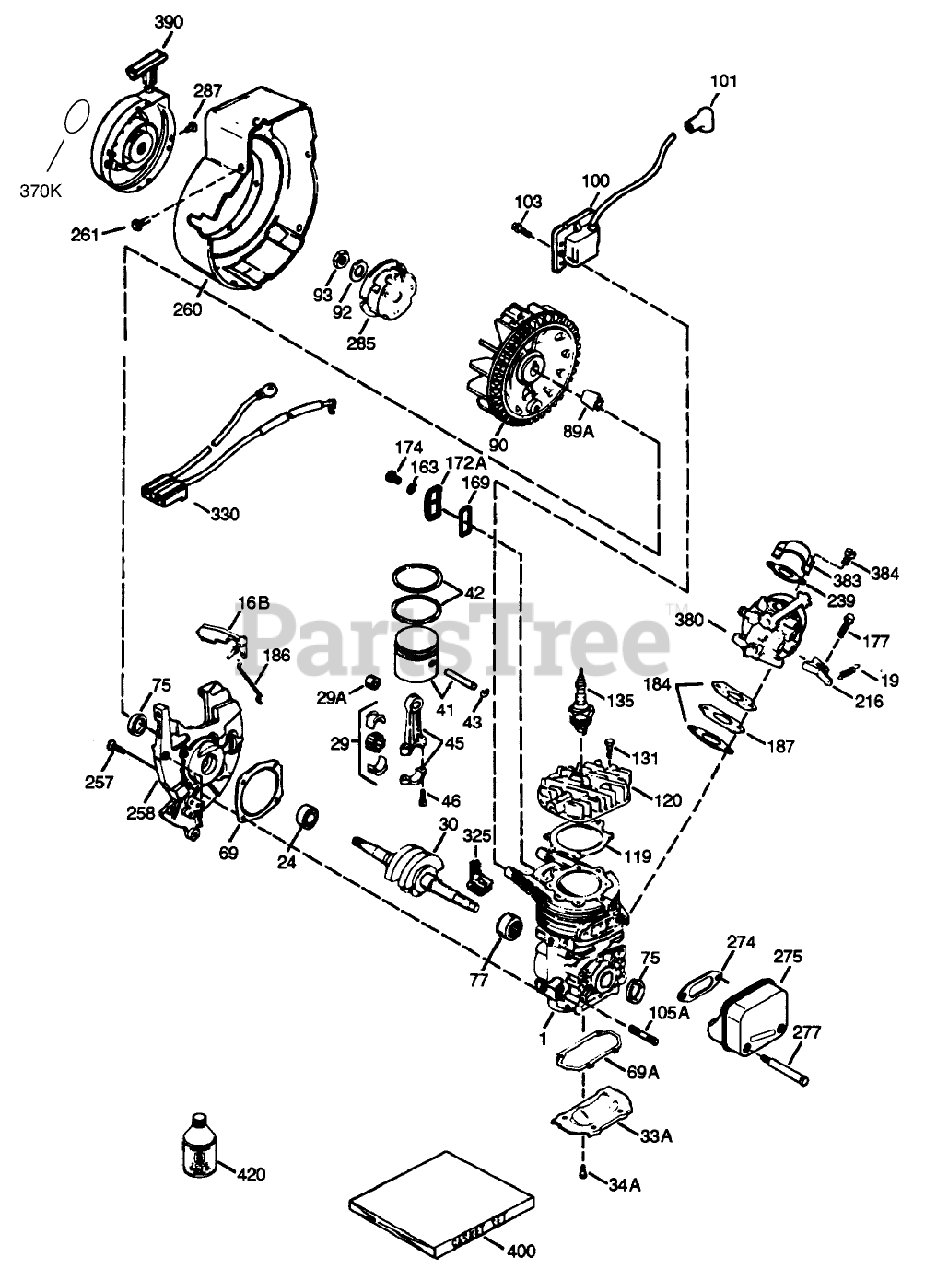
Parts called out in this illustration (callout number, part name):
1	Cylinder (Order Short Block if Replacement is Needed)
16B	Vane-Air
19	Spring-Extention
24	Bearing-Ball
29	Needle Bearing and Liner Set (37 Needles)
29A	Bearing-Cartridge
30	Crankshaft
33A	Plate-Cover
34A	Screw (T-25, 10-24 x 1/2)
41	Piston (Incl. Ref. #43)
42	Ring Set
43	Ring-Retaning
45	Rod Assy.-Connecting (Incl. Ref. #3, 3A 3B)
46	Bolt-Rod, Connecting
69	Gasket-Cover, Cylinder
69A	Gasket-Plate, Cover
75	Seal-Oil
77	Bearing-Cartridge
89A	Blade (20 inch)
90	CARB BODY S
92	Washer-Belleville
93	Nut-Flywheel
100	Solid State Ignition (Incl. 101)
101	Cover-Spark Plug
103	Screw (T-15, 10-24 x 15/16)
119	Gasket-Head, Cylinder
120	Head-Cylinder
131	Screw (T-30, 1/4-20 x 3/4)
135	Spark Plug-Resistor (R C J 8Y)
163	Washer
169	Cover-Compression, Release
172A	Cover-Release, Compression
174	Screw (T-25, 10-24 x 1/2)
177	Screw (5/32 Allen, 1/4-20 x 1)
184	Gasket-Carburetor
186	Governor-Link
187	Spacer
216	Lever-Adjusting, Rpm
239	2060A77 WIZARD ROTA
257	Screw (T-30, 1/4-20 x 5/8)
258	Base Ass-y-Blower Housing (Incl Ref. #20)
260	Housing-Blower
261	Screw (1/4-20 x 1/2)
274	Exhaust Gasket
275	Muffler (Incl. Ref. #274 277)
277	Screw (1/4-20 x 2-3/4)
285	Cup-Starter
287	Screw (8-32 x 21/64)
325	Clip-Wire
330	Harness-Wire
370K	Decal-Tecumseh Logo for Top of Recoil Starter
380	Carburetor (Incl. ref. #184)
383	Baffle-Carburetor
384	Screw (T-25, 10-32 x 5/8)
390	Rewind Starter ASM
400	Gasket Set
420	2-Cycle Oil (8oz)
